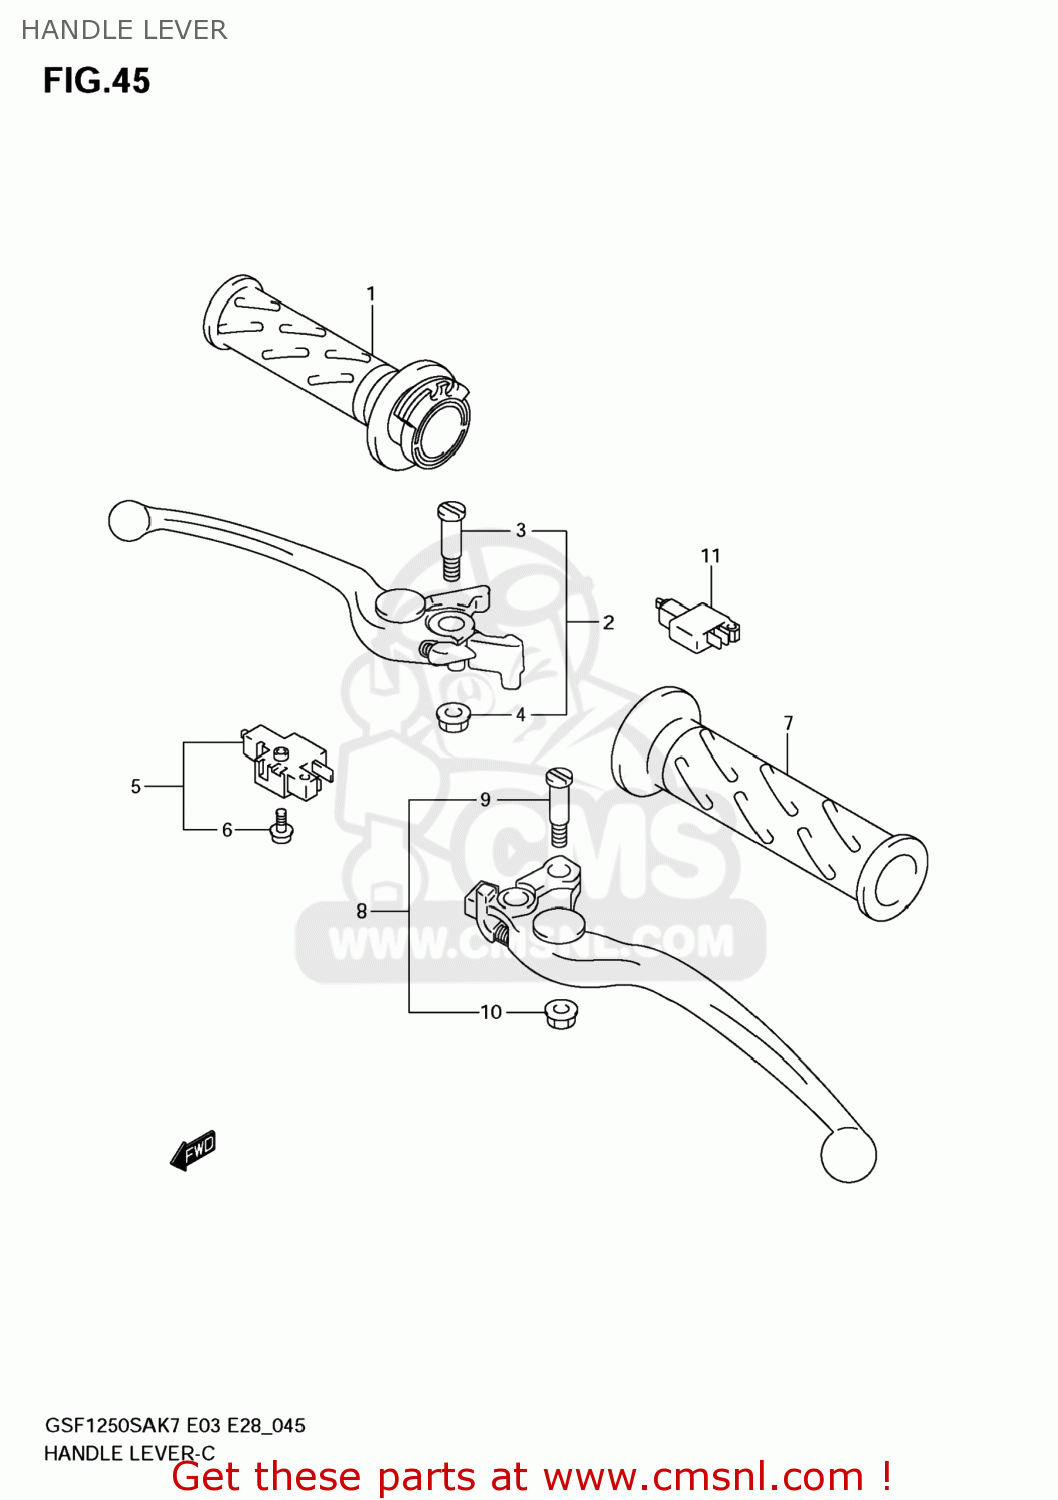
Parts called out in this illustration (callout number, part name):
1	GRIP,THROTTLE
2	LEVER ASSY,BRA
3	BOLT,PIVOT
4	NUT
5	SWITCH ASSY,ST
6	SCREW
7	GRIP,LEFT
8	LEVER ASSY,CLU
9	BOLT,PIVOT
10	NUT
11	SWITCH ASSY,CLUTCH
